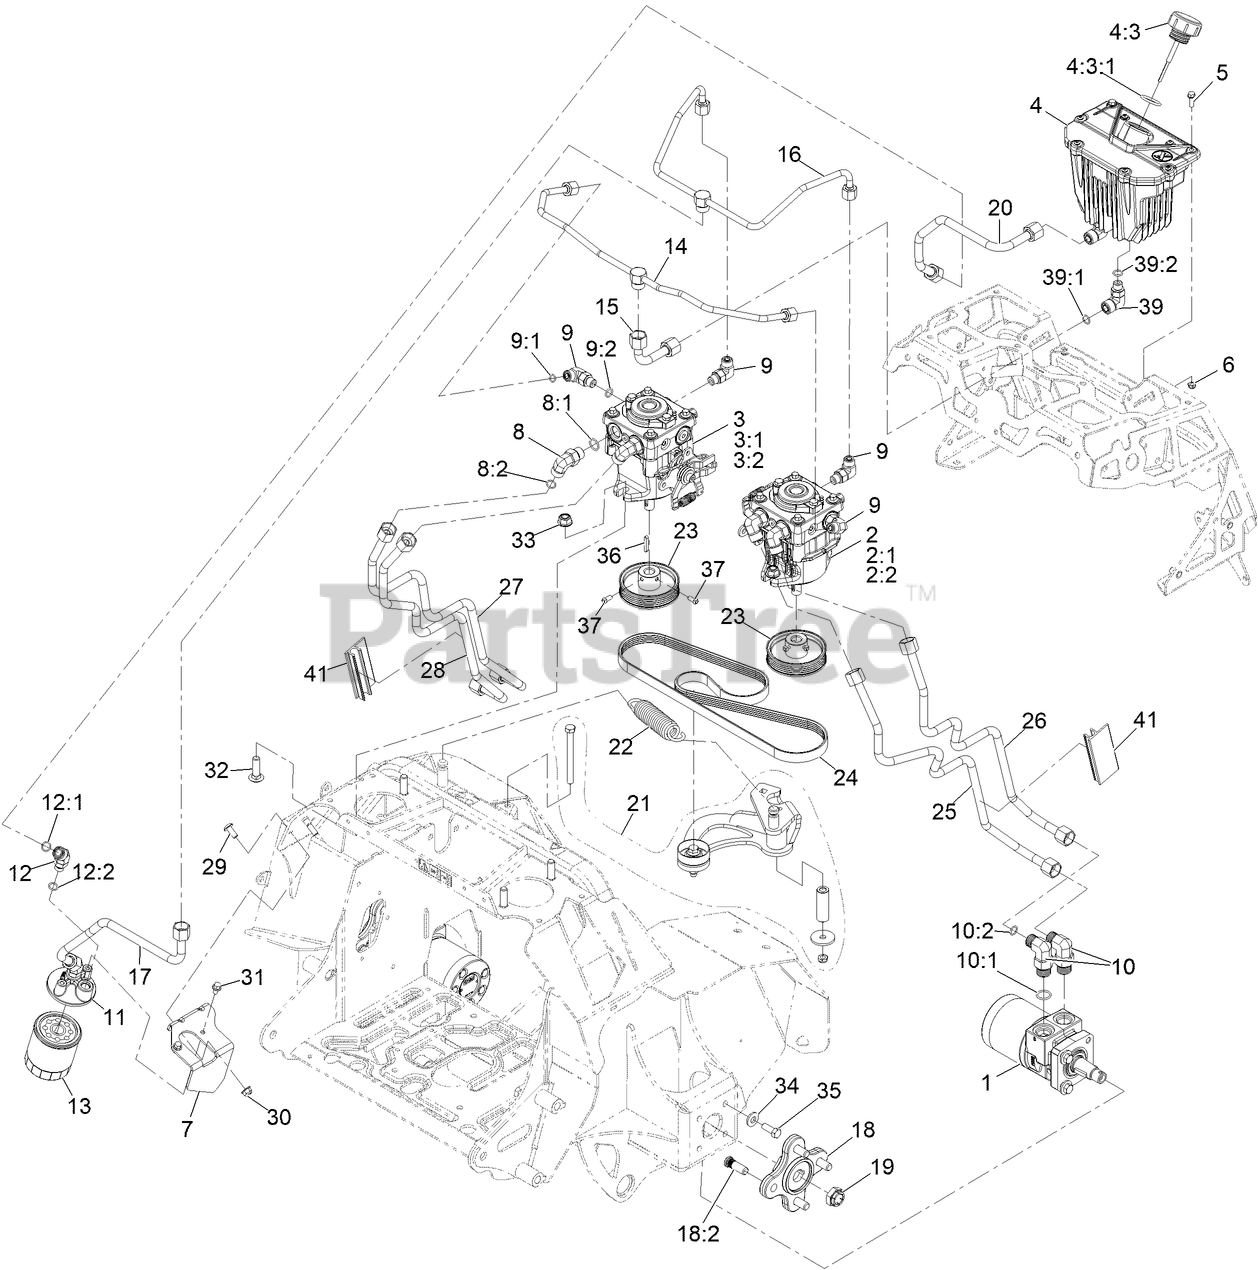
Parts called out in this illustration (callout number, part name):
1	MOTOR-WHEEL
2	PUMP-HYDRAULIC 10CC
2:1	KIT, 10CC/12CC PUMP KIT
2:2	SEAL OVERHAUL KIT
3	PUMP-HYDRAULIC 10CC
3:1	KIT, 10CC/12CC PUMP KIT
3:2	SEAL OVERHAUL KIT
4	ASM, Hydraulic Reservoir
4:3	Cap, Hydraulic
5	SCREW-HWH
6	NUT-LOCK, NI
7	MOUNT, FILTER
8	FITTING-ELBOW, 90 DEG
8:1	O-RING
8:2	O-RING
9	FITTING-ELBOW, 90 DEG
9:1	O-RING
9:2	O-RING
10	FITTING-ELBOW, 90 DEG
10:1	O-RING
10:2	O-RING
11	HEAD-FILTER
12	Adapter
12:1	O-RING
12:2	O-RING
13	FILTER-25 MICRON, BI-DIRECTIONAL
14	LINE, HYDRAULIC, CASE TEE
15	LINE, HYDRAULIC, CASE
16	LINE, HYDRAULIC, CHARGE TEE
17	LINE, HYD. CHARGE
18	ASM-HUB AND STUDS
18:2	STUD-WHEEL
19	NUT-LOCK
20	LINE, HYD. SUPPLY
21	ASM, IDLER ARM
22	SPRING, EXTENSION
24	BELT, PVK5
25	KIT-STE HYD LINE LT REAR B-A
26	KIT-STE HYD LINE LT FRNT A-B
27	KIT-STE HYD LINE RT REAR B-B
28	KIT-STE HYD LINE RT FRNT A-A
29	SCREW-TORX
30	NUT-HF, NI
31	SCREW-HHF
32	BOLT-CARR
33	NUT-HF, NI
34	WASHER-BELLEVILLE
35	SCREW-HH
36	KEY, 5MM X 5MM X 29MM
37	Screw-SQH
39	Fitting-HYD, 90 DEG
39:1	O-RING
39:2	O-RING
41	SPACER-HYDRAULIC TUBE
